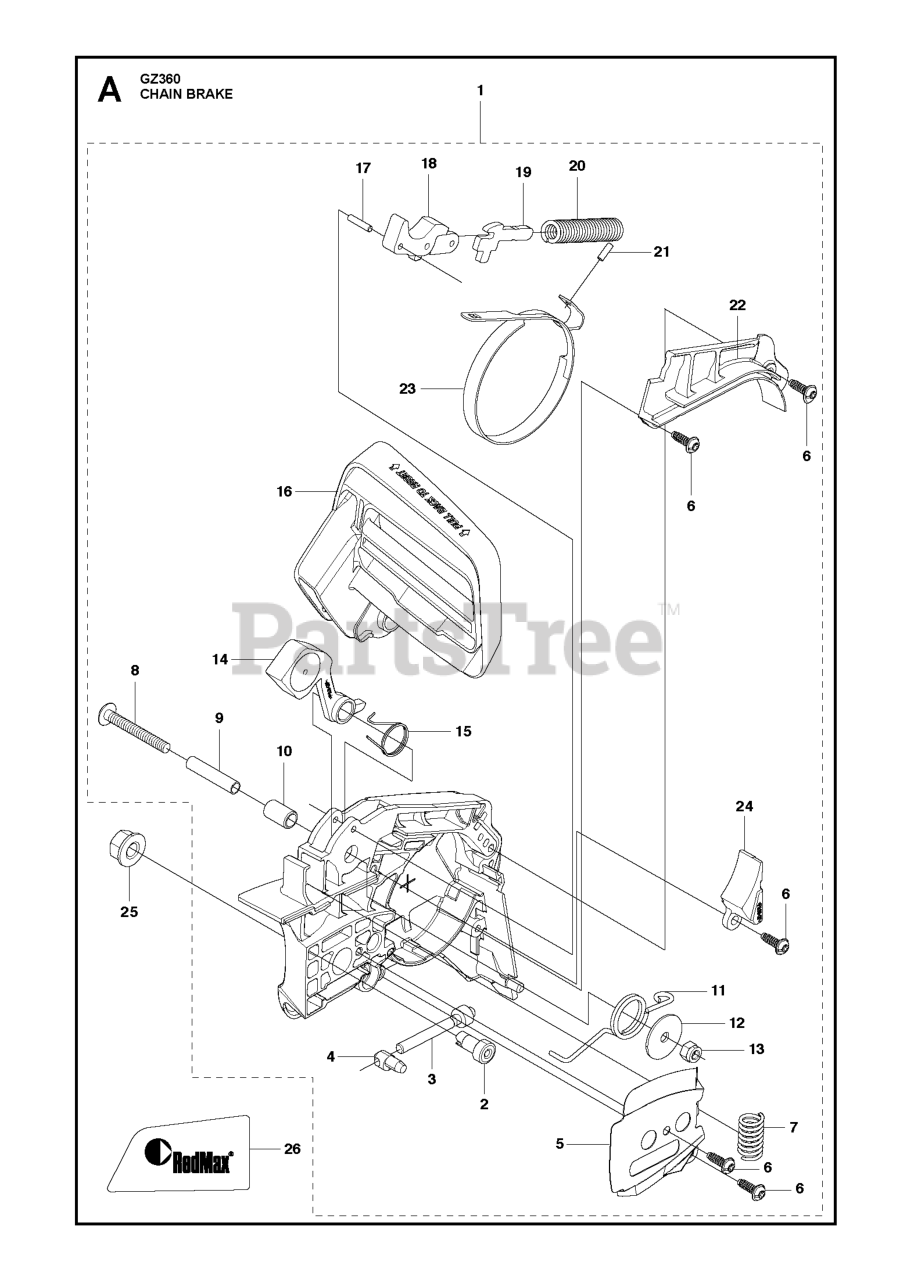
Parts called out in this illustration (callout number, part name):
1	CLUTCH COVER ASSY
3	SCREW
6	SCREW
8	SCREW
9	SPACER INNER
10	SPACER
11	RETURN SPRING
12	WASHER
15	SPRING
16	HAND GUARD GZ360-US
17	ROLLER
18	BRAKE LEVER
19	ARM
20	RETURN SPRING
21	ROLLER
22	COVER LID ZENOAH NEW RED
23	BRAKE BAND
25	NUT M8 FLANGE
26	DECAL CLUTCH COVER
